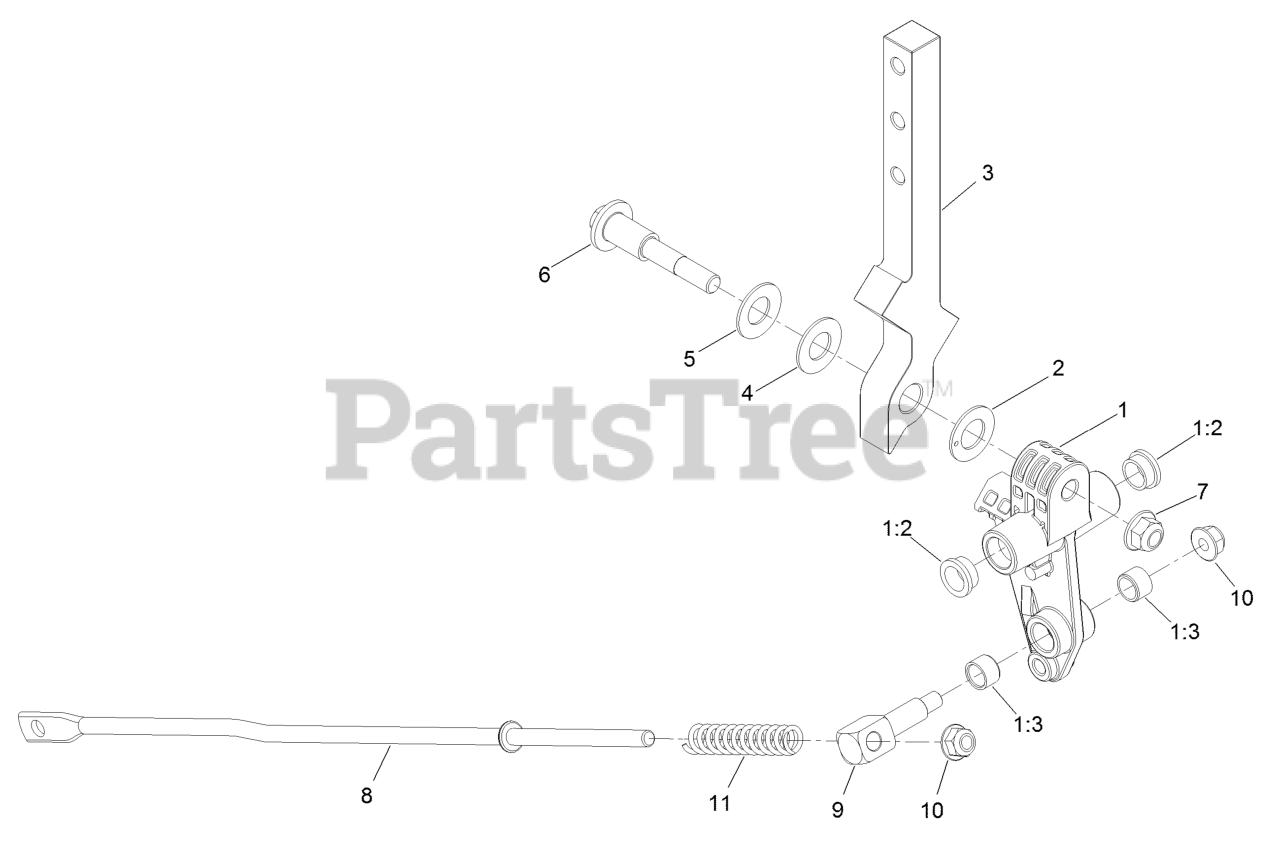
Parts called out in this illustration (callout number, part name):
1	CONTROL ARM ASM
1:2	BUSHING
1:3	BUSHING-SLEEVE
2	WASHER-FRICTION
3	ARM-CONTROL
5	WASHER-BELLEVILLE
6	BOLT-PIVOT
7	NUT-HF, NI
8	LINK-CONTROL
10	NUT-HF, NI
11	SPRING-RETURN, NEUTRAL
